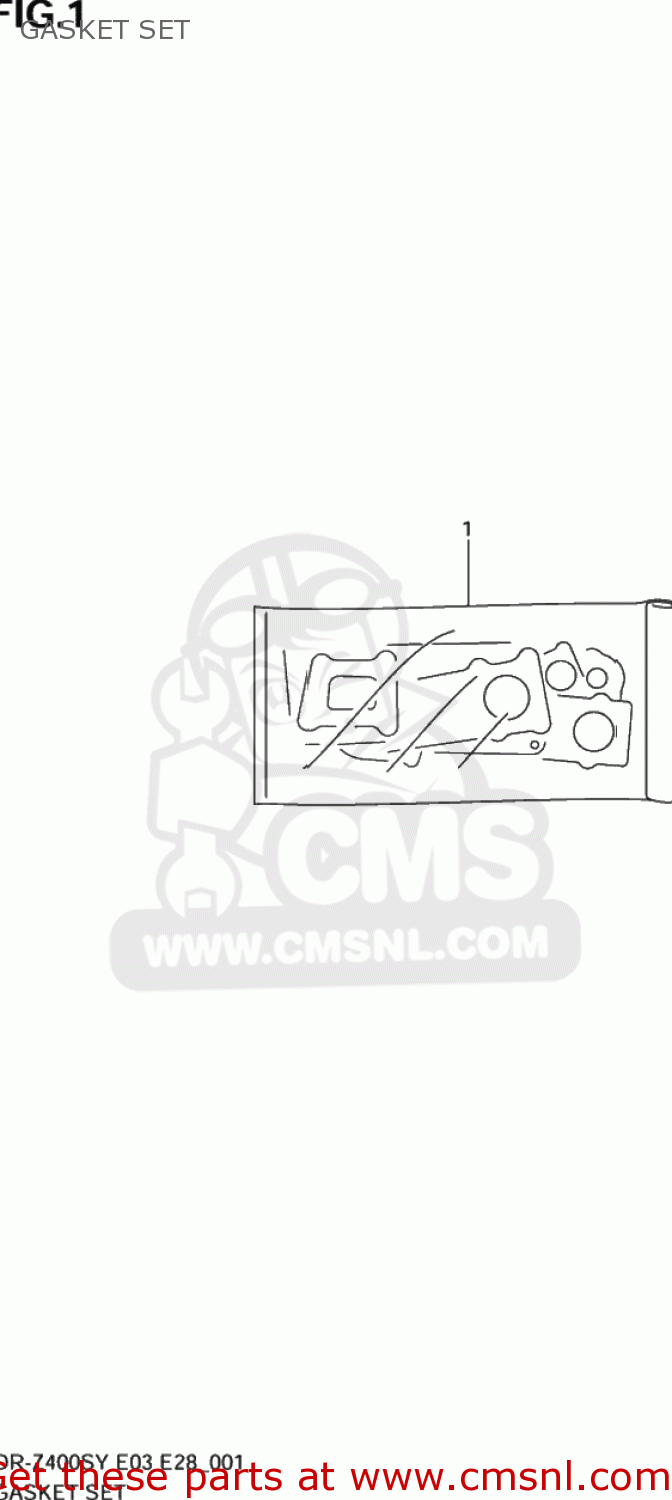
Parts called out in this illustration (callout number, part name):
1	GASKET SET (NAS)
2	GASKET,CYLINDER HEAD (NAS)
3	GASKET,CYL HEAD COVER (NAS)
4	GASKET,CYLINDER (NAS)
5	GASKET,CLUTCH COVER (NAS)
6	GASKET,MAGNETO COVER (NAS)
7	O RING,CLUTCH COVER OUTER
8	GASKET,TENSIONER ADJUSTER (NAS)
9	GASKET,EXHAUST PIPE
10	WASHER(10.6X25.5X2.3)
11	O RING(D:2.4,ID:11)
12	O RING(D:1.9,ID:13)
13	O RING(D:3.1,ID:16.8)
14	O RING(D:3.1,ID:32.7)
15	O RING(D:2.4,ID:52.6)
16	O-RING
